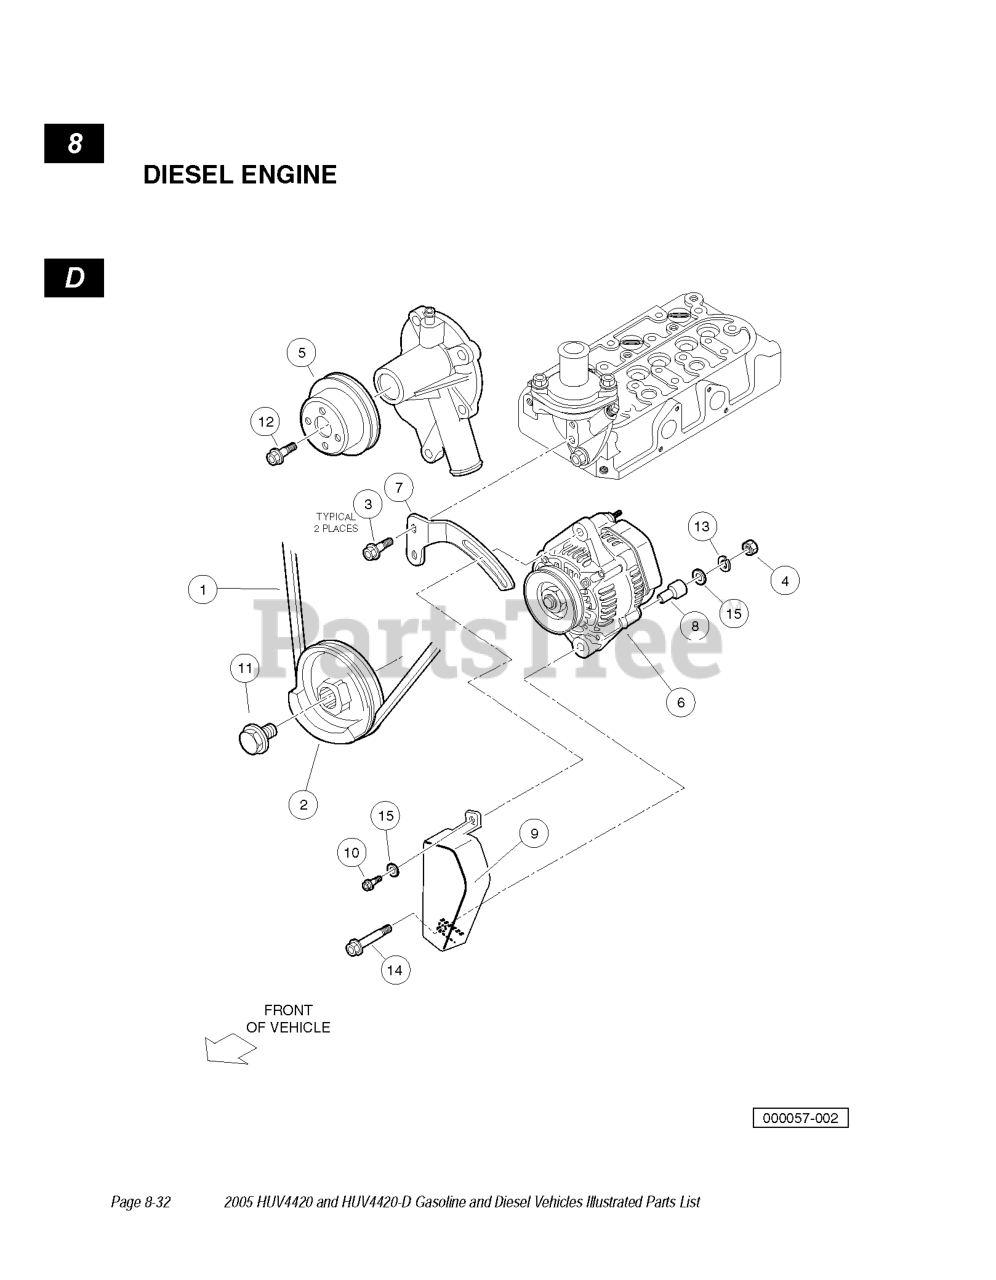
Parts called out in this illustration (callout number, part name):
2	PULLEY, FAN DRIVE
3	BOLT, M6X1X20
4	NUT-ALT-LOWER
5	PULLEY, WATER PUMP
6	ALTERNATOR ASSY, D722 40 AMP
7	STAY, ALTERNATOR ASSY, D722
8	COLLAR, ALTERNATOR ASSY, D722
9	COVER, ALTERNATOR ASSY, D722
10	BOLT, ALT, D722, ADJUSTER
11	BOLT, ALT, D722, DRIVE PULLEY
12	BOLT, D722, DRIVE PULLEY
13	WASHER-ALT-LOCK
14	BOLT-ALT-LOWER
15	WASHER-ALT-UPPER
